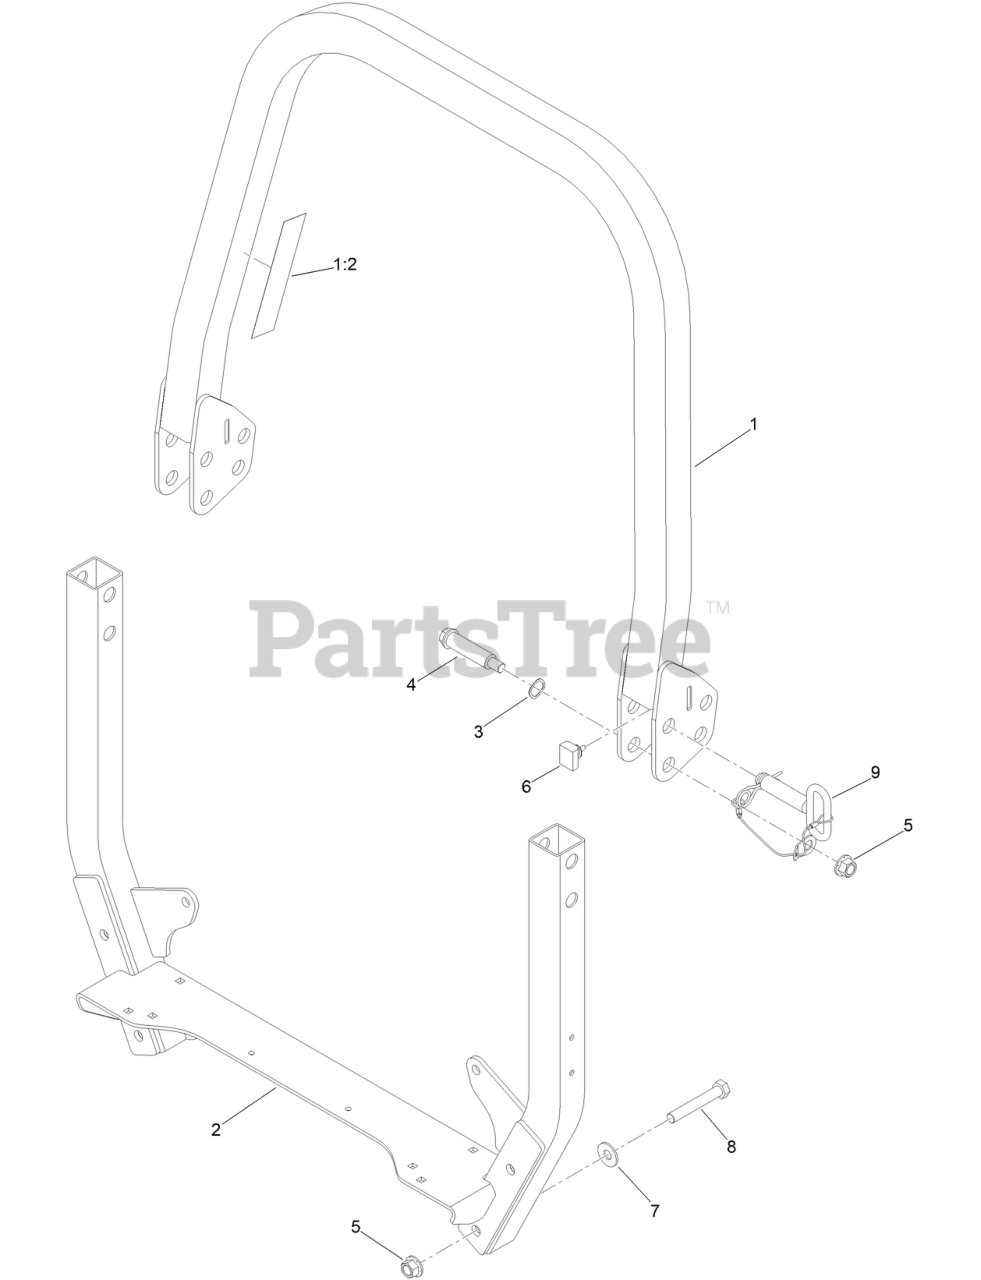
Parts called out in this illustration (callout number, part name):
1	UPPER ROPS ASM
1:2	DECAL-WARNING
2	LOWER ROPS ASM
3	WASHER-WAVE
4	BOLT-SHOULDER
5	NUT-LOCK
6	BUMPER-ROPS
7	WASHER-SPRING
8	SCREW-HH
9	PIN-ROPS, ASM
